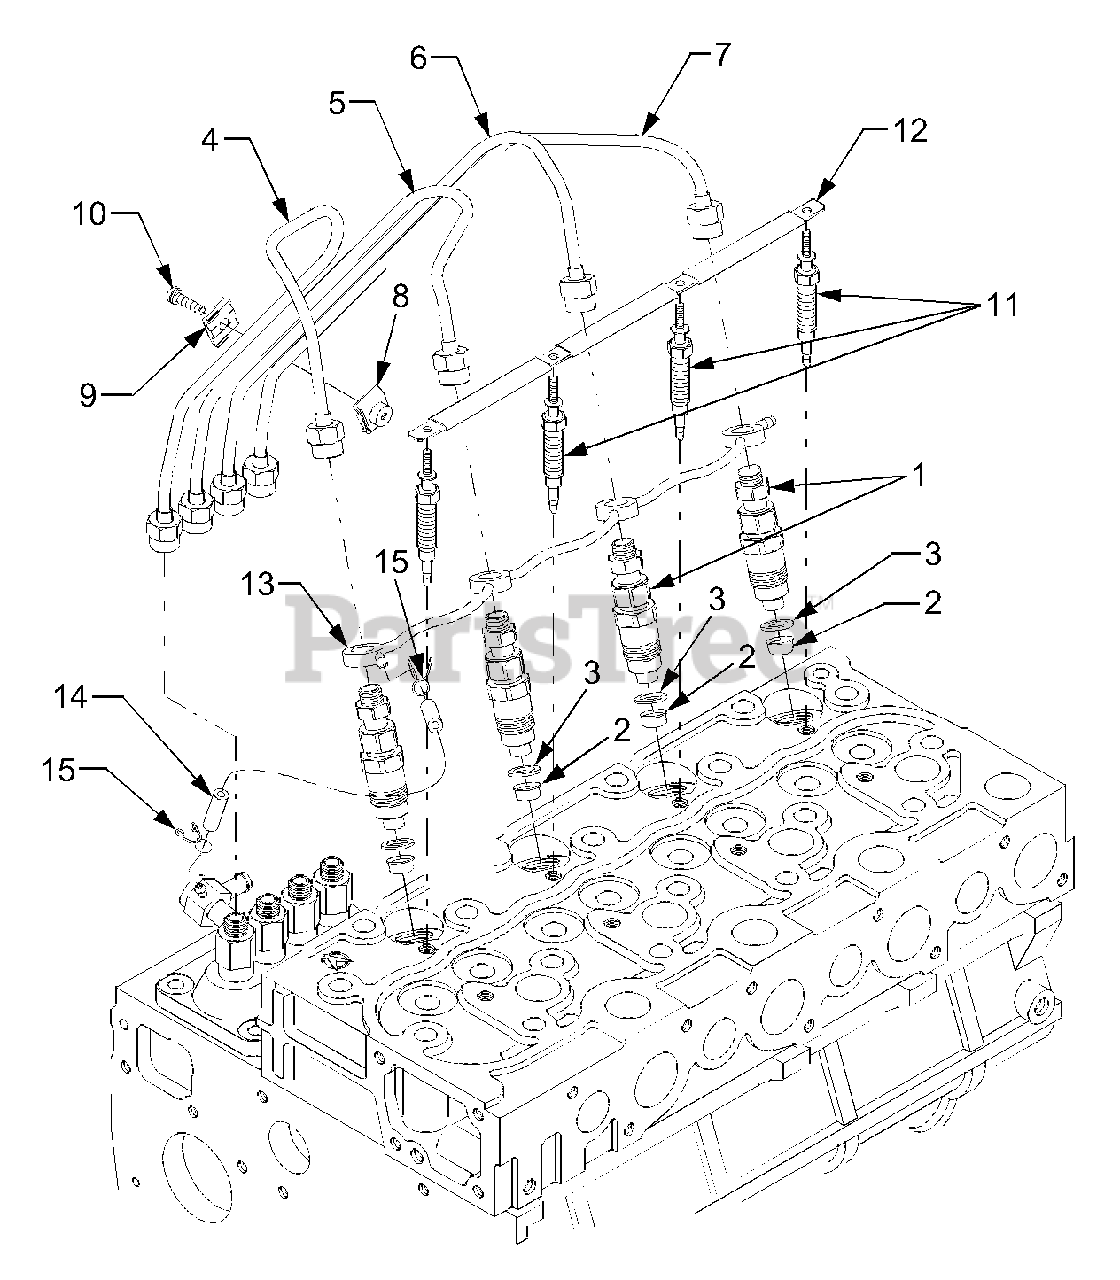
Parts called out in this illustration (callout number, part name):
1	Nozzle Holder Ass'y
4	Pipe 1, Injection
5	Pipe 2, Injection
6	Pipe 3, Injection
7	Pipe 4, Injection
8	Clamp 1, Pipe
9	Clamp 2, Pipe
11	Plug, Glow
12	Cord, Glow Plug
13	Over Flow Pipe Ass'y
